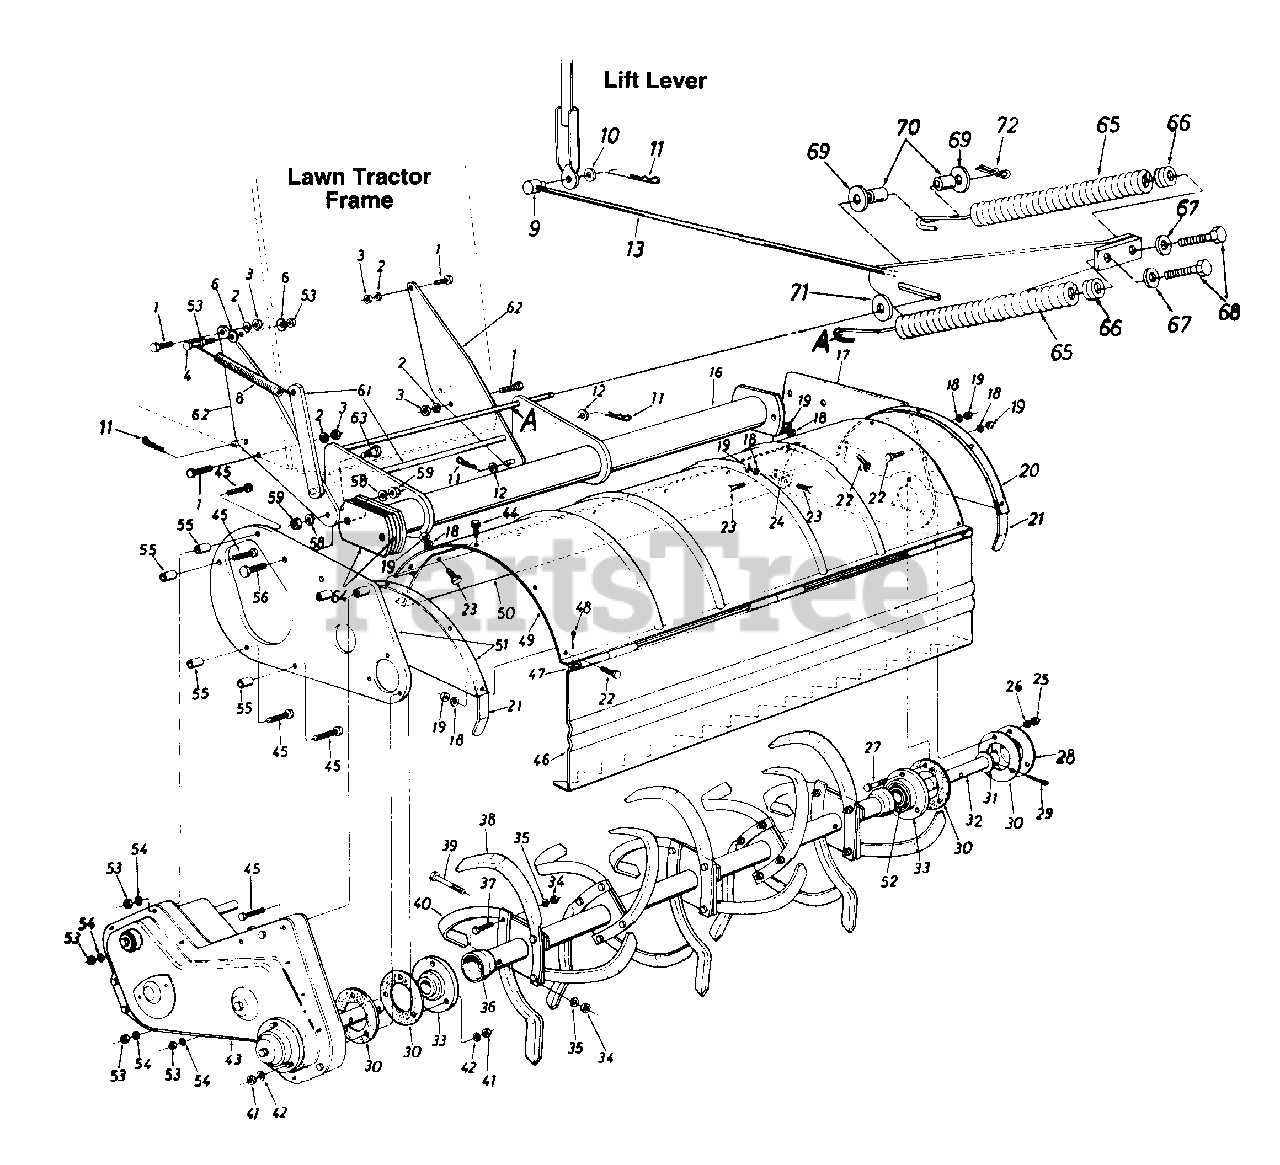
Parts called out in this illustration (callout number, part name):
1	Hex Bolt 3/8-24 x .88" Lg.
2	L-Wash. 3/8" I.D. - H.D.
3	Hex Nut 3/8-24 Thd.
4	Hex Bolt 1/4-20 x 1.25" Lg.
6	Bell-Wash. 1/4" I.D.
8	Ext. Spring 7.75" Lg.
9	Adjustment Ferrule 1/2-13 Thd.
10	Fl-Wash. .64" I.D. x 1.24" O.D. x .06"
11	Intern. Cotter Pin 1/2" Dia.
12	Fl-Wash. .51" I.D. x 1.0" O.D. x .06"
13	Lift Bracket Ass'y.
14	Comp. Spring 1.5" O.D. x 15" Lg.
15	Fl-Wash. .51" I.D. x 1.5" O.D. x .075"
16	Pivot Bracket Assembly
19	Hex Nut 5/16-24 Thd.
23	Hex Bolt 5/16-24 x .62" Lg.
24	Chute Pivot Bracket
25	Hex L-Nut 5/16-18 Thd.
27	Hex Bolt 5/16-18 x 1" Lg. (Grade 5)
30	Gasket for Brg. Housing
31	Fl-Wash. 1.25" I.D. x 2.0" O.D. x .06"
32	Tine Shaft 1.25" Dia. x 6.25" Lg.
33	Bearing Housing w/Bearing
38	Tine 14" x 5/16"
39	Hex Bolt 3/8-24 x 2.25" Lg.
40	Tine 14" x 5/16"
43	Chain Case Ass'y. Comp.
44	Hex TT-Tap Scr. 5/16-18 x .62" Lg.
45	Hex Bolt 1/4-20 x 2.75" Lg.
48	Cotter Pin 1/8" Dia. x 1" Lg.
53	Hex Nut 1/4-20 Thd.
54	L-Wash. 1/4" I.D.
55	Spacer .28" I.D. x .62" O.D. x .9" Lg.
56	Hex Bolt 1/2-20 x 1.5" Lg.
58	L-Wash. 1/2" I.D.
59	Hex Nut 1/2-20 Thd.
61	Idler Brkt. Support Arm Ass'y.
62	Pivot Brkt. Support
63	Shoulder Bolt
64	Support Plate
65	Helper Spring
66	Spring Insert
67	Fl-Wash. .34" I.D. x .68" O.D.
68	Hex Bolt 5/16-18 x 3.25" Lg.
69	Fl-Wash. .51" I.D. x 1.5" O.D.
70	Split Spacer .505" I.D. x .57" Lg.
71	Fl-Wash. .531" I.D. x 1.25" O.D.
72	Internal Cotter Pin 1/2" Dia.
